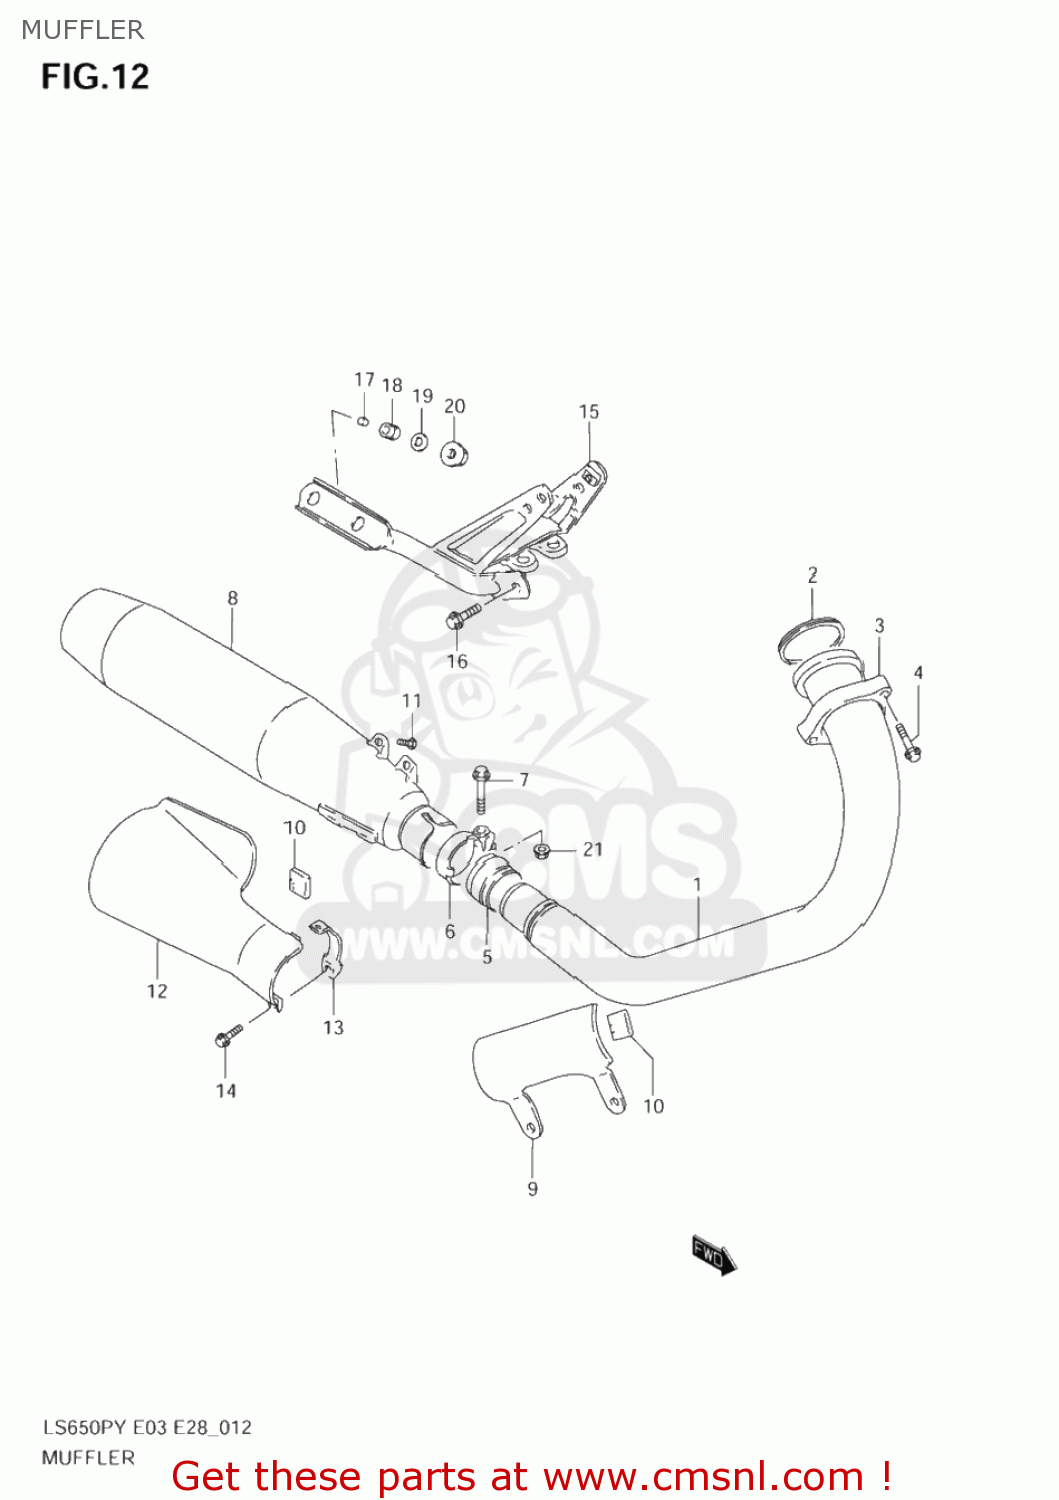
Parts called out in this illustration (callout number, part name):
1	PIPE,EXHAUST
2	GASKET,EXHAUST PIPE (NAS)
3	CLAMP,EXHAUST PIPE
4	BOLT(8X35)
5	CONNECTOR,MUFFLER
6	CLAMP,MUFFLER,R(L:42.7)
7	BOLT
8	BODY,MUFFLER
9	COVER,EXHAUST PIPE
10	GASKET (NAS)
11	SCREW
12	COVER,MUFFLER
13	CLAMP,MUFFLER COVER
14	BOLT
15	STAY,MUFFLER SUPPORT
16	BOLT
17	SPACER(8.5X12X11)
18	CUSHION
19	WASHER
20	NUT
21	NUT
